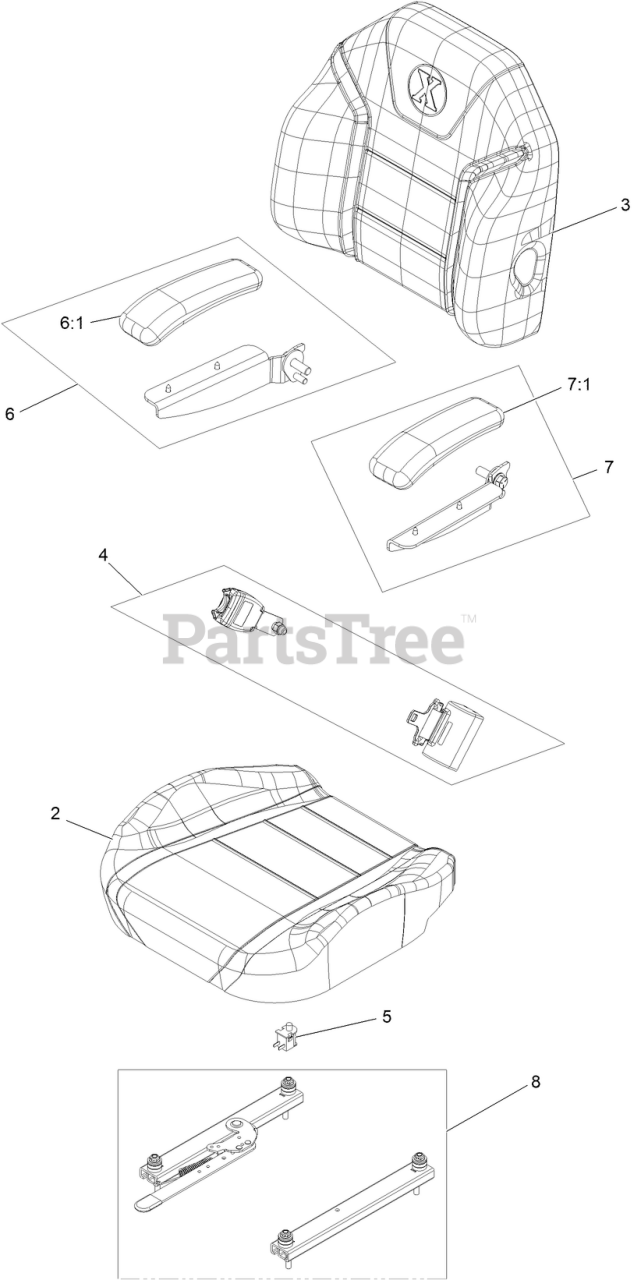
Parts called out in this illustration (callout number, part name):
2	COVER, LOWER
3	COVER, UPPER
4	KIT-SEAT BELT
5	SWITCH-BAIL
6	RH Arm Rest Kit
6:1	CUSHION-REST, ARM
7	LH Arm Rest Kit
7:1	CUSHION-REST, ARM
8	ASM-Track
